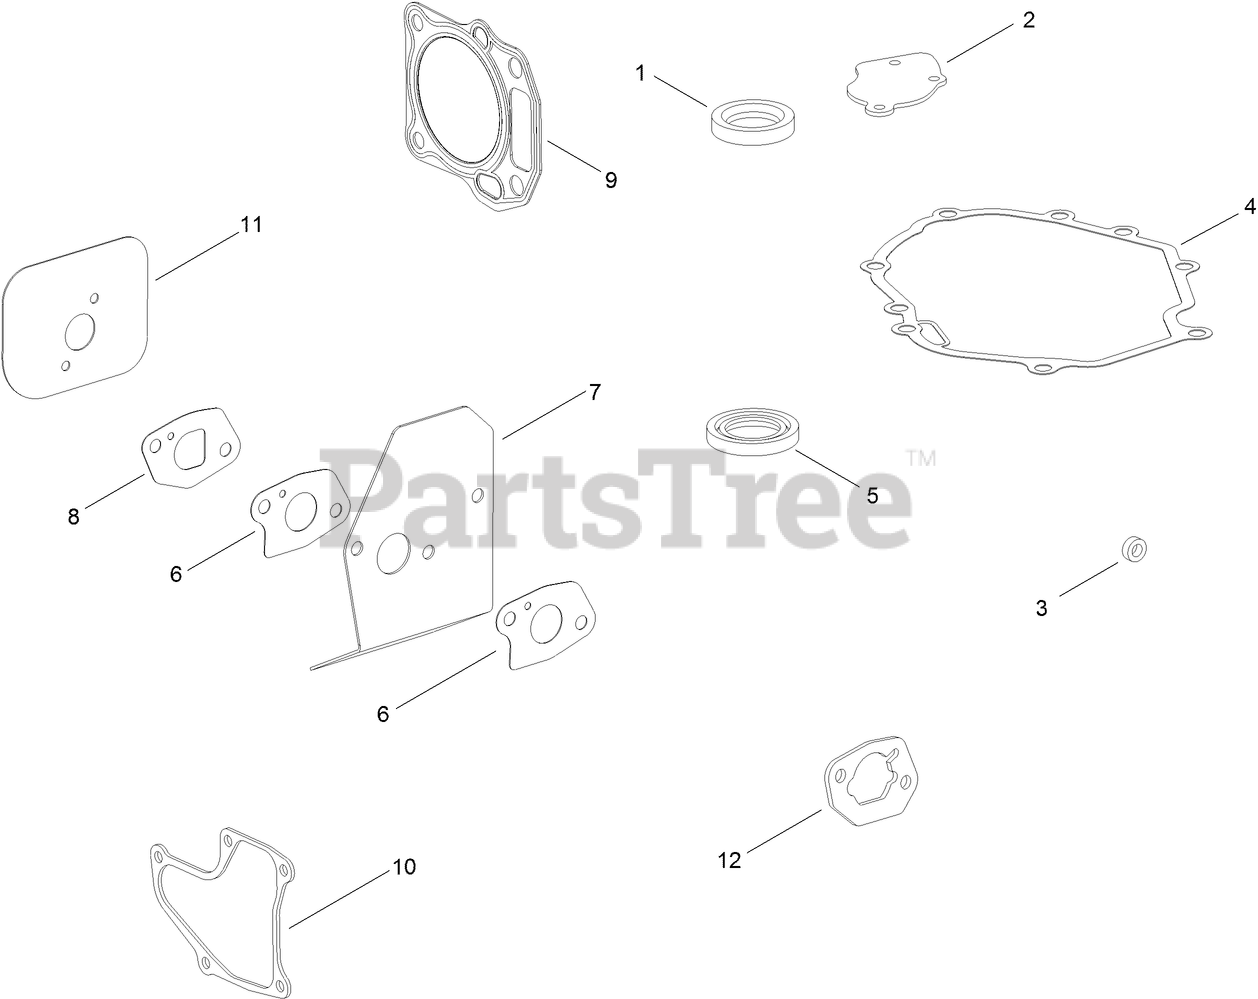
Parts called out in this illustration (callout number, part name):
1	SEAL-OIL
2	GASKET-BREATHER
3	SEAL-OIL
4	GASKET-COVER, CASE
5	SEAL-OIL
6	GASKET-CARBURETOR
7	INSULATOR-CARBURETOR
8	GASKET-INTAKE
9	GASKET-HEAD
10	GASKET-VALVE COVER
11	GASKET-EXHAUST
12	GASKET-AIR CLEANER
